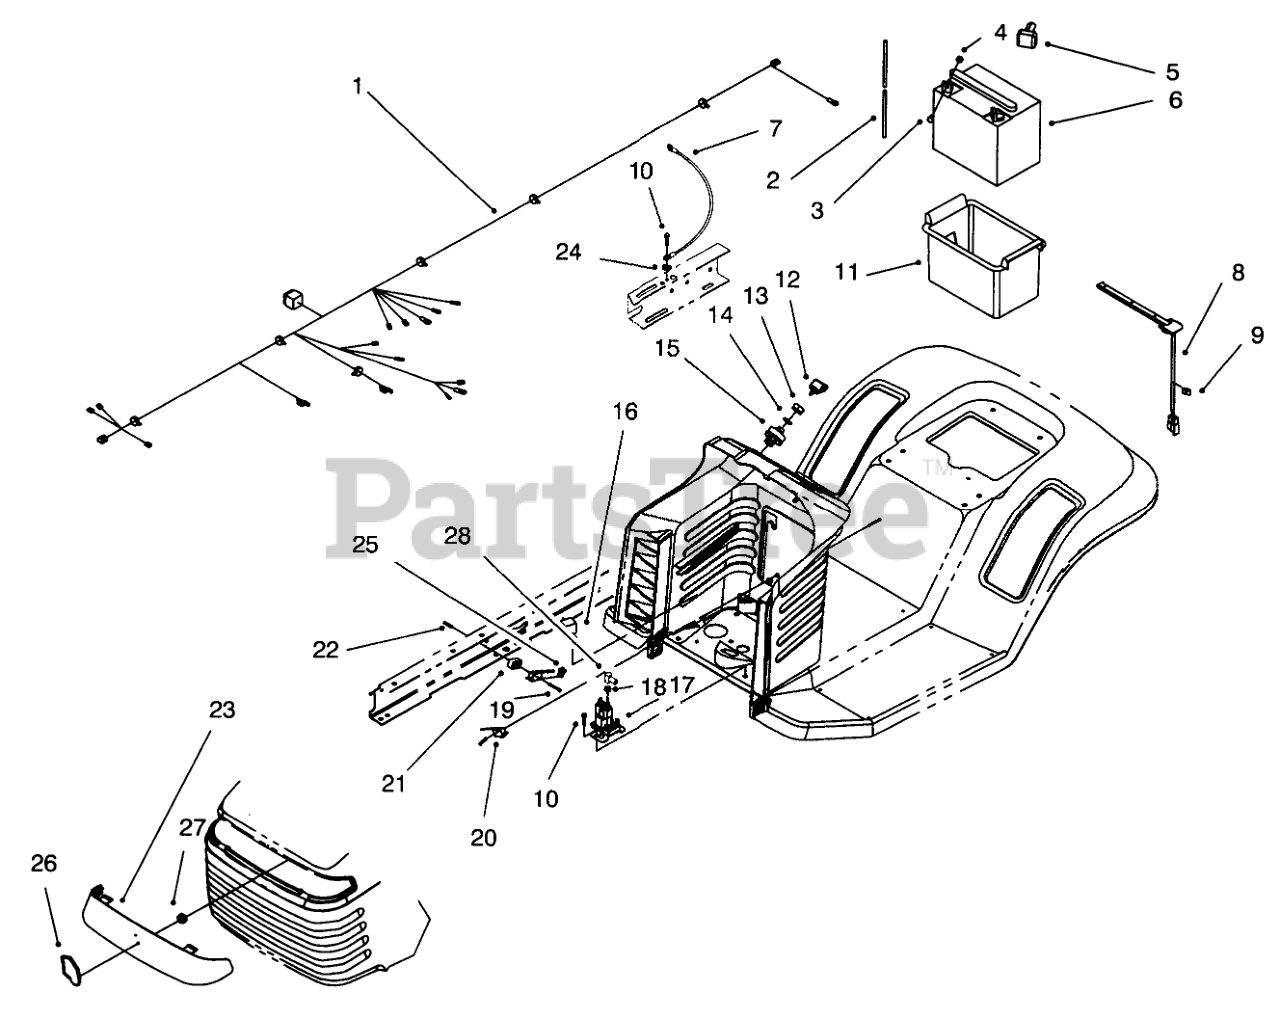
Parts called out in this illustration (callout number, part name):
1	WIRE HARNESS
2	TUBE-BATT DRAIN/80-2600
3	SCREW-HH
4	NUT-WING
5	BOOT-TERMINAL
6	Battery
7	WIRE ASM
8	SWITCH-SEAT
9	CLIP-RETAINER, WIRE
10	SCREW-HWH
11	BOX-BATTERY
12	KEY-IGNITION
13	NUT-HH
14	WASHER-TOOTH, INTERNAL
15	Key Switch ASM
16	RELAY
17	Solenoid
18	NUT-KEPS
19	SCREW-HH
20	SWITCH-MICRO
21	SPACER
22	NUT-SPEED
23	LENS-HEADLIGHT
24	WASHER-LOCK/EXT
25	PLUNGER-SEAL
26	EMBLEM-GRILLE WHEELHORSE
28	BOOT-TERMINAL INSULATOR
